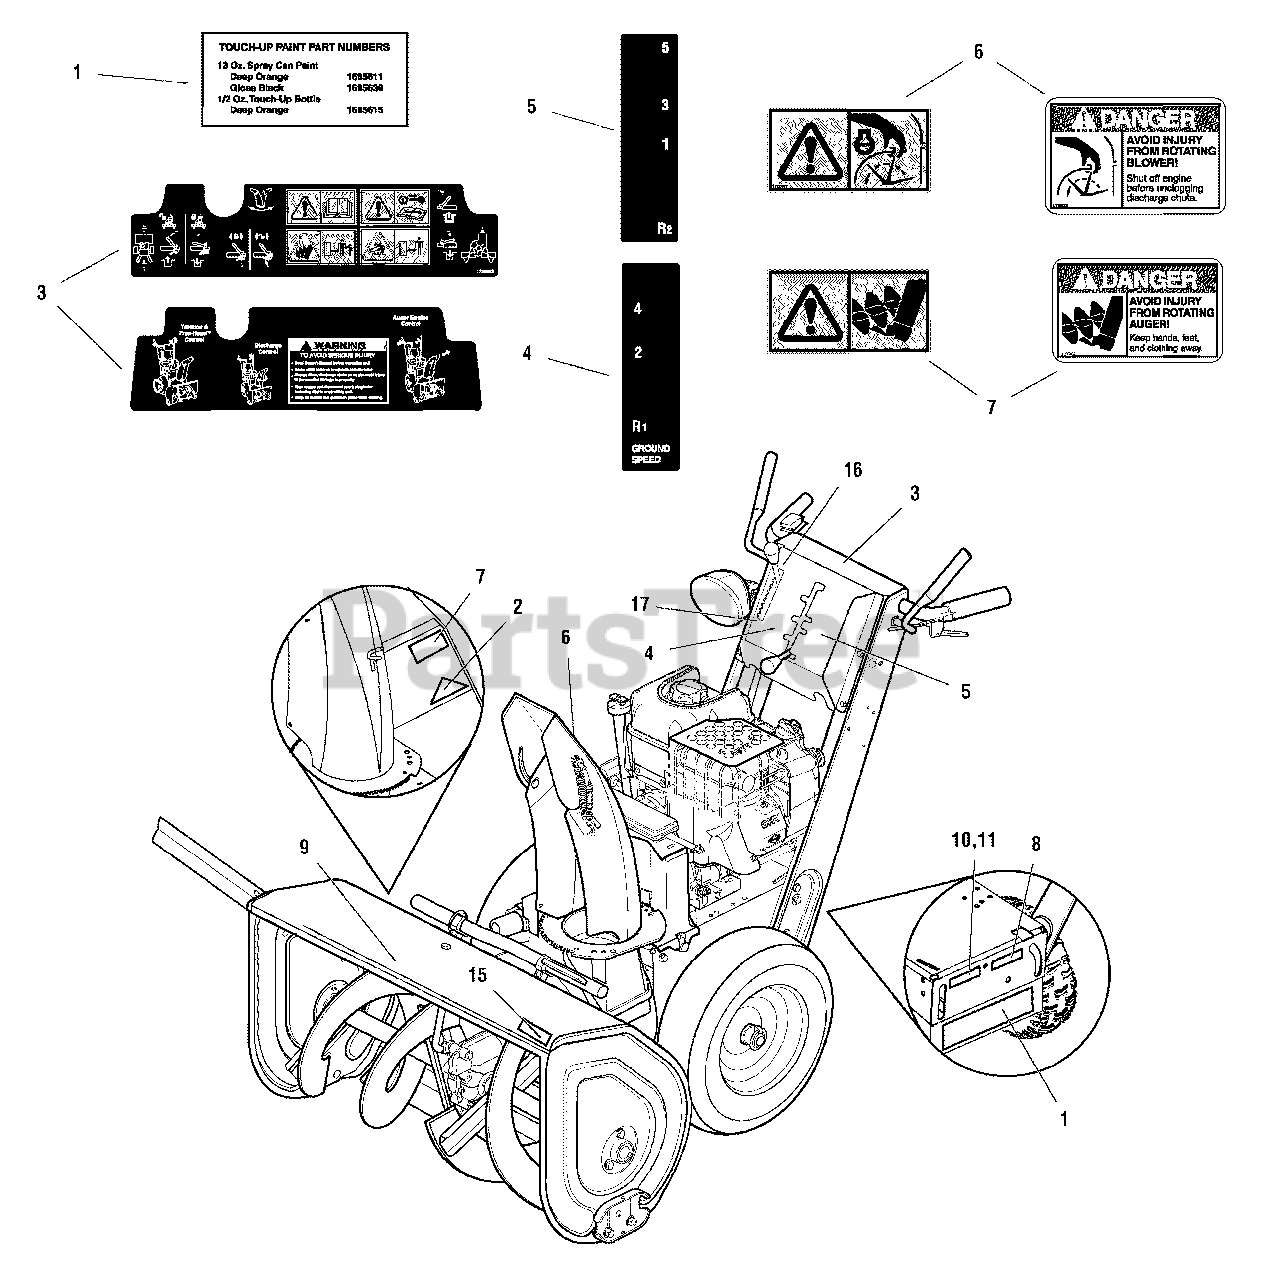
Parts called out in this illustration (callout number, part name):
1	DECAL, Touch Up Paint, Orange, Black, Red
3	DECAL, Dashboard EZ Turn Channel Handles
3	DECAL, Dash Instruction
4	DECAL, 4 2 R1 Ground Spped RH, LF
5	DECAL, 5 3 R2 Shift Pattern LH, LF
6	DECAL, DANGER Auger - Use Snow Stick
7	DECAL, Danger Avoid Injury from Auger
8	DECAL, Patent Snowthrower
9	DECAL, Simplicity Stripe 24" Long 2007 Snow
9	DECAL, Simplicity Stripe 28" Long 2007 Snow
9	DECAL, Simplicity Stripe 32" Long 2007 Snow
9	DECAL, Simplicity Stripe 38" Long 2007 Snow
15	DECAL, Signature Pro 1524P
15	DECAL, Signature Pro 1628P
15	DECAL, Signature Pro 1732P
15	DECAL, Signature Pro 1738P
16	DECAL, Deflector Control Up
17	DECAL, Deflector Control Down
